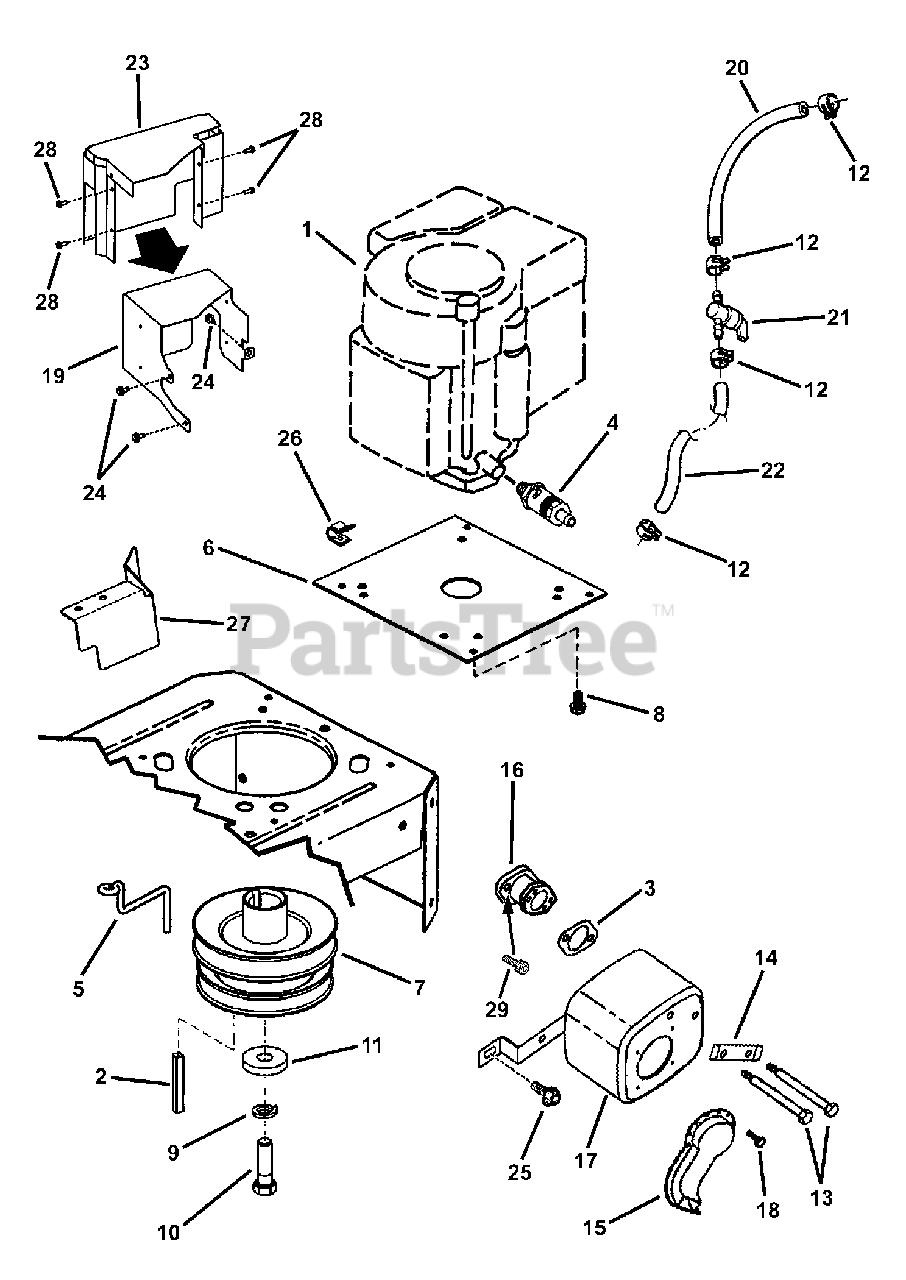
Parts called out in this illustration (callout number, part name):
2	KEY, 1/4" Square x 2"
3	GASKET, Exhaust
4	ASSEMBLY, Oil Valve
5	GUIDE, Engine Belt
6	PLATE, Engine, HOZ
7	PULLEY, Engine
8	SCREW, 3/8-16 x 1" Hex Washer Self-tap
9	WASHER, 7/16 Split Lock
10	SCREW, 7/16-20 x 1-1/2" Hex Head Cap, GR 5
11	WASHER, .468 x 1.38 x .25 Flat (special)
12	CLAMP, Fuel Line
13	BOLT, 5/16-18 x 4" Shoulder
14	SCREW LOCK
15	DEFLECTOR, Muffler
16	ADAPTER, Muffler
17	MUFFLER, 14.5 HP B&S Engine
18	SCREW, #8-18 x 1/2" Hex Head Sheet Metal
19	WELDMENT, Heat Shield- B&S
20	HOSE, Fuel, 1/4 I.D. x 14" long
21	VALVE, Fuel
22	HOSE, Fuel, 12-1/2" long
23	WELDMENT, Heat Shield- B14 Euro
24	SCREW, 1/4-20 x 1/2" Hex Washer Self-Tap
25	BOLT, 5/16-18 x 5/8" Hex Flange Lock, GR 5
26	HARNESS CLIP (vinyl covered)
27	HEAT SHIELD, Fender
28	SCREW, #10-24 x 1/2" Hex Washer Self-Tap (Torx)
29	SCREW, 5/16-18 x 3/4" Socket Head Cap, GR 8
